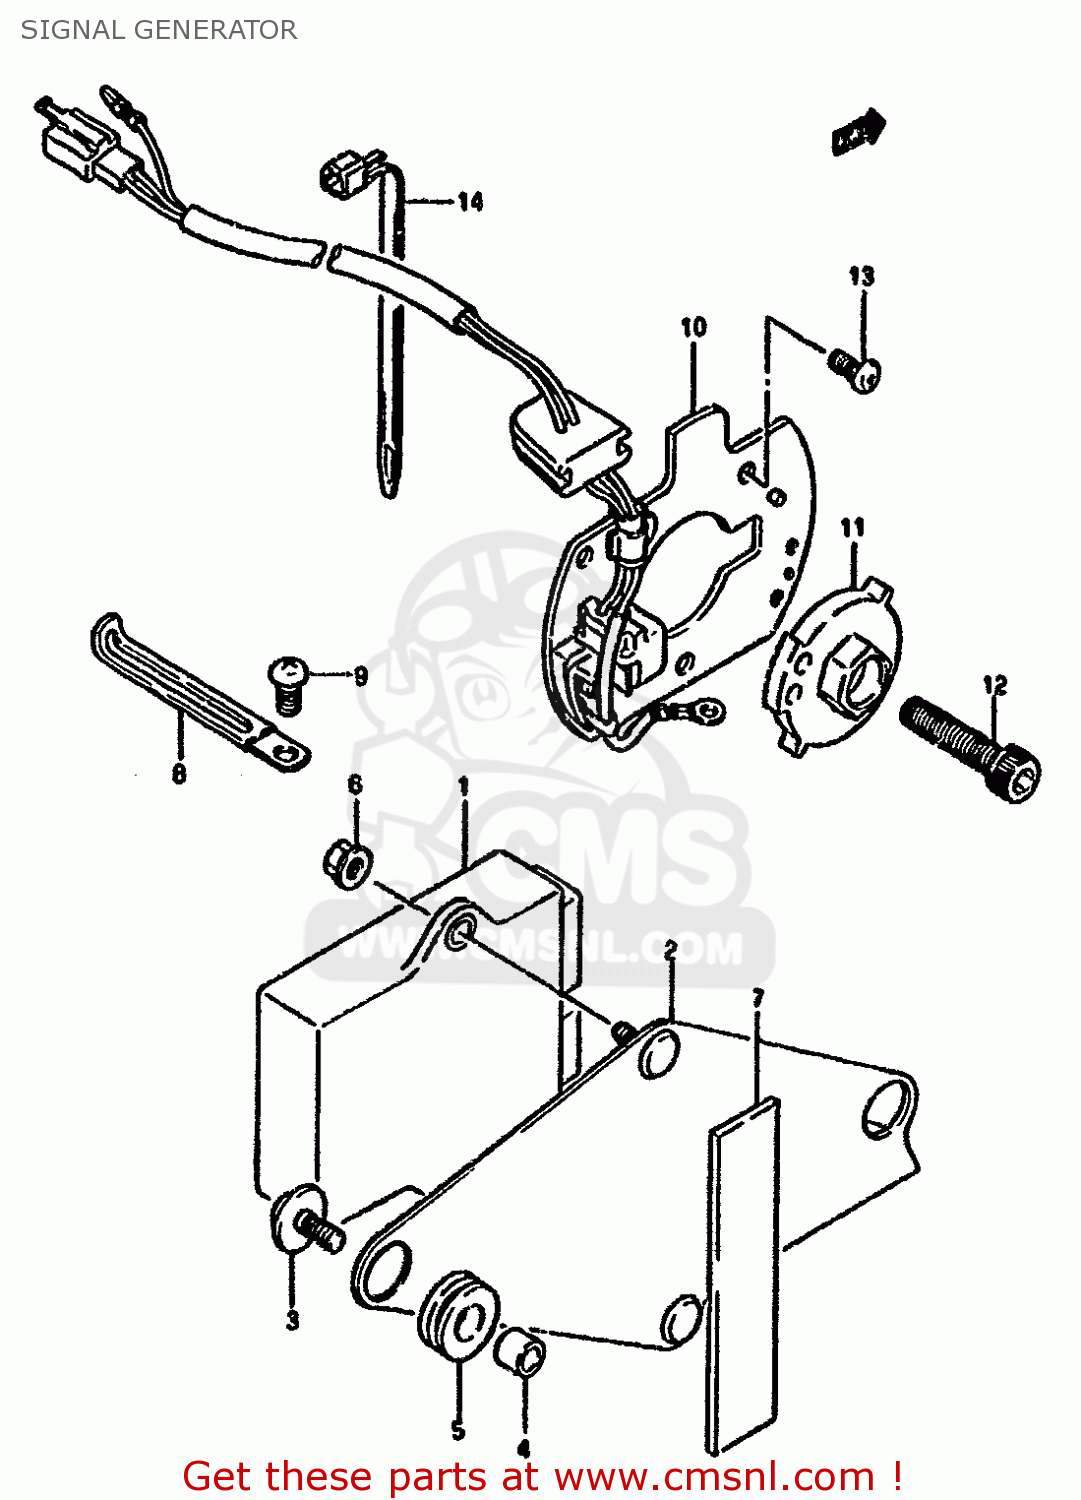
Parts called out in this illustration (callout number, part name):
1	IGNITER UNIT
2	PLATE COMP,IGNITER
3	SCREW(6X16)
4	SPACER(6.1X9X7.5)
5	CUSHION
6	NUT
7	PROTECTOR,20X9
8	CLAMP
9	SCREW
10	GENERATOR ASSEMBLY,SIGNAL
11	ROTOR,SIGNAL
12	BOLT
13	SCREW
14	CLAMP(L:125)
